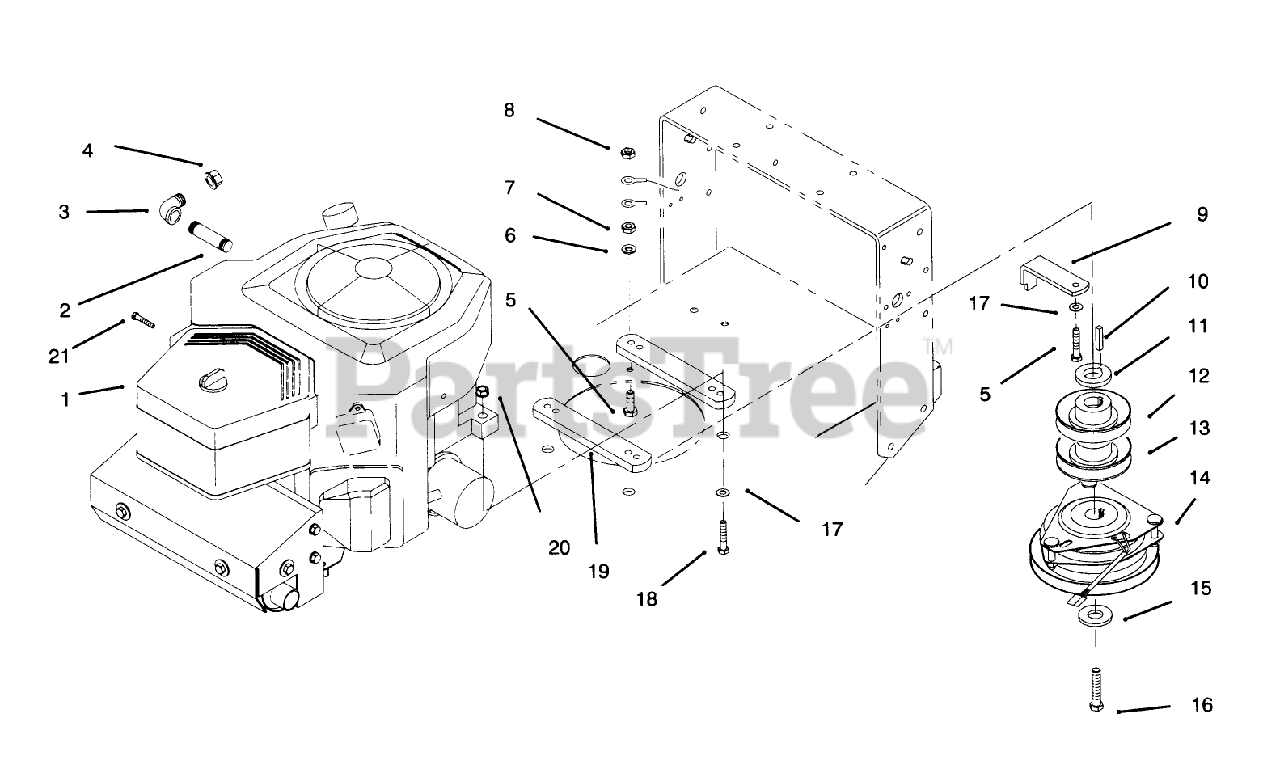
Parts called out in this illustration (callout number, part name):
1	ENGINE - 18 HP KOHLER
2	NIPPLE
3	ELBOW-STREET, 90 DEG
4	CAP-PIPE
5	SCREW-HH
6	WASHER-LOCK
7	NUT-HEX, SIDE DEFORM
8	NUT-KEPS
9	Retainer-Clutch
11	SPACER - PULLEY
12	SHEAVE-UPPER HALF
13	SHEAVE-LOWER HALF
14	CLUTCH/BRAKE
15	WASHER
16	SCREW-HH
17	WASHER-PLAIN
18	SCREW-HH
19	SPACER - ENGINE
20	NUT-LOCK, CONE
21	SCREW-TAP
